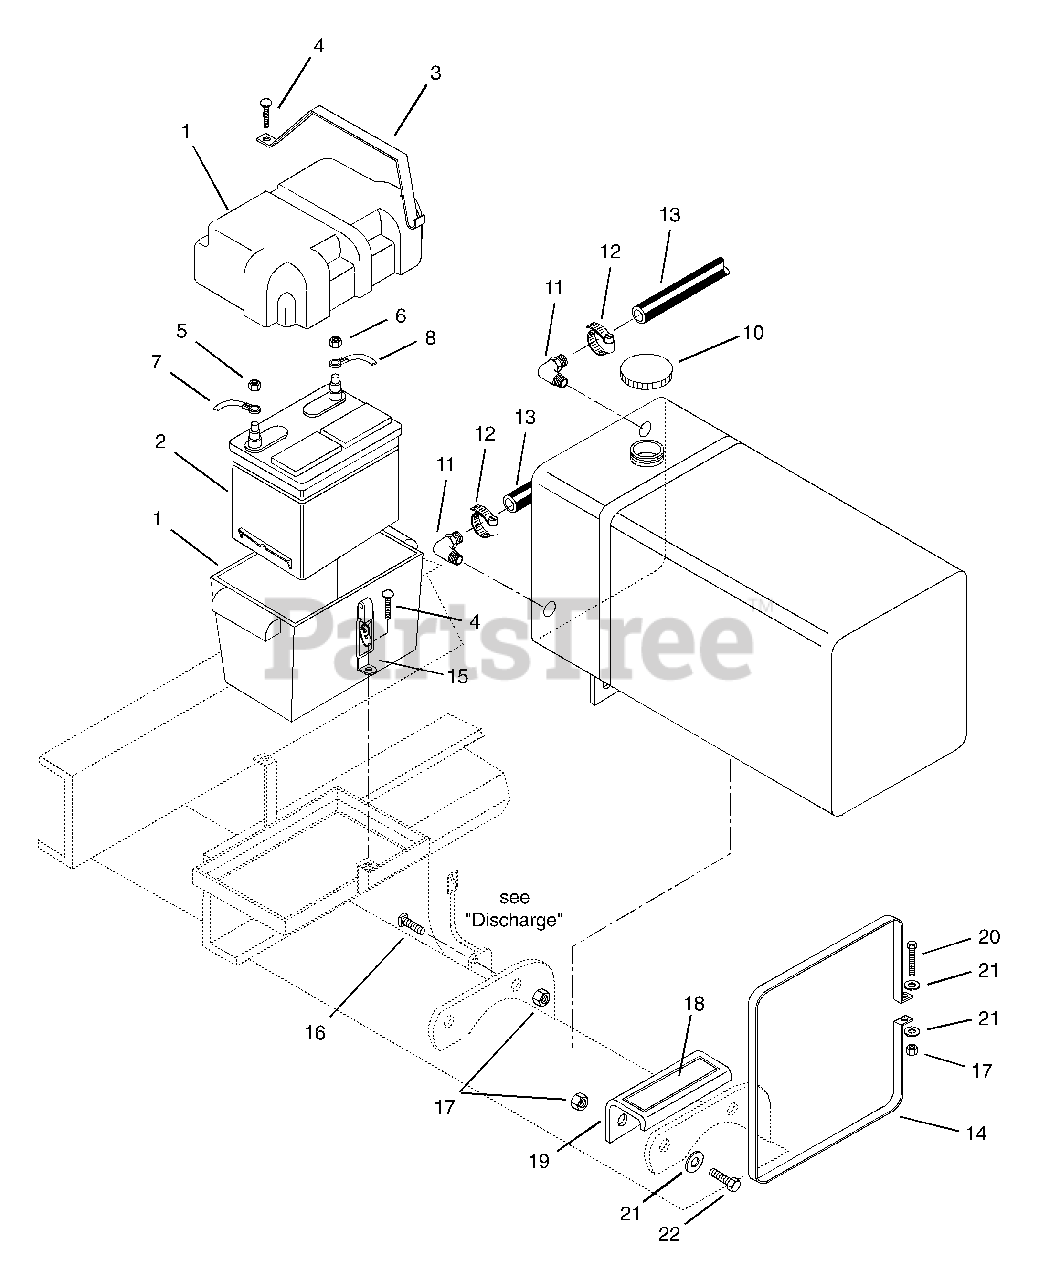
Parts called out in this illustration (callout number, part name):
1	Box, Battery
2	Battery, Marine Type
3	Strap-Battery Hold Down
4	Bolt-Round Head Square Neck .31-18 x 1.75 Grade 5
5	Nut-Hex .31-18
6	Nut-Hex .38-16
7	Cable-Battery (Negative)
8	Cable-Battery (Positive)
9	Gas Tank Weldment
11	Elbow-90 Degree, Pipe w/Barbed Inserts
12	Camp-Hose
13	in. Gas Line-Bulk
14	Strap-Tank
15	Latch Assembly-Battery Hold Down
16	Bolt-Hex .38-16 x 1.75 Grade 5
17	Nut-Locking-Center .38-16
18	Gasket
19	Mount-Tank
20	Bolt-Hex .38-16 x 3.00 Grade 5
21	Washer-Flat-Steel .438 x 1.00 x .083
22	Bolt-Hex .38-16 x 1.25 Grade 5
